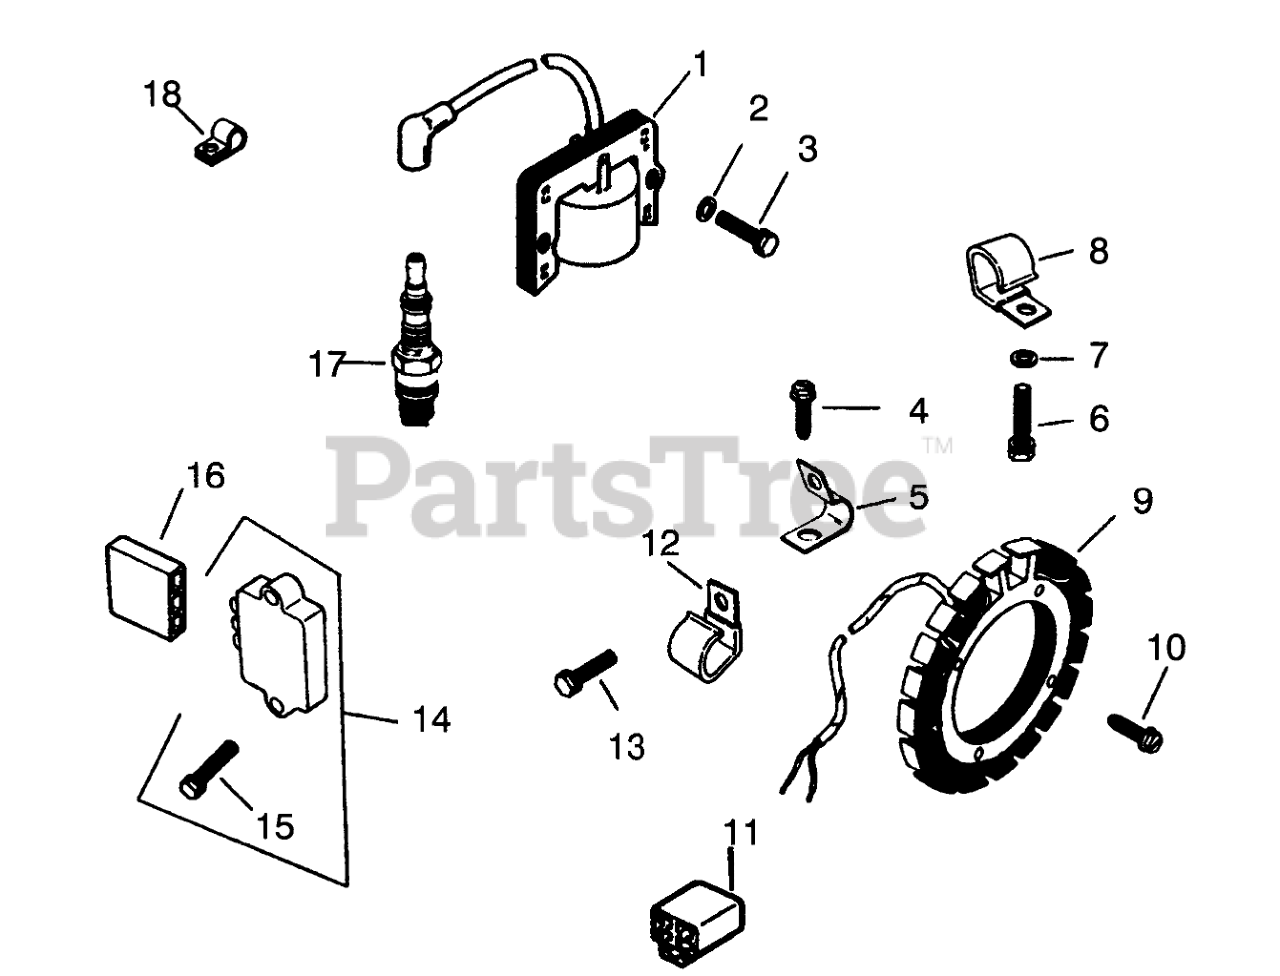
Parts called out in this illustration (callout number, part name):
1	Module-Ignition
2	Washer
3	Screw
4	Screw-Hex. Hd.
6	Screw
7	Washer
8	Clip
9	Kit-Stator 15 am (Incl. Ref. #8)
10	Screw
11	Connector
12	CLIP
13	SCREW-HH
14	Regulator-Rectifier
15	Screw
16	Connector
17	Plug-Spark
18	Clip-Hi-Tension
